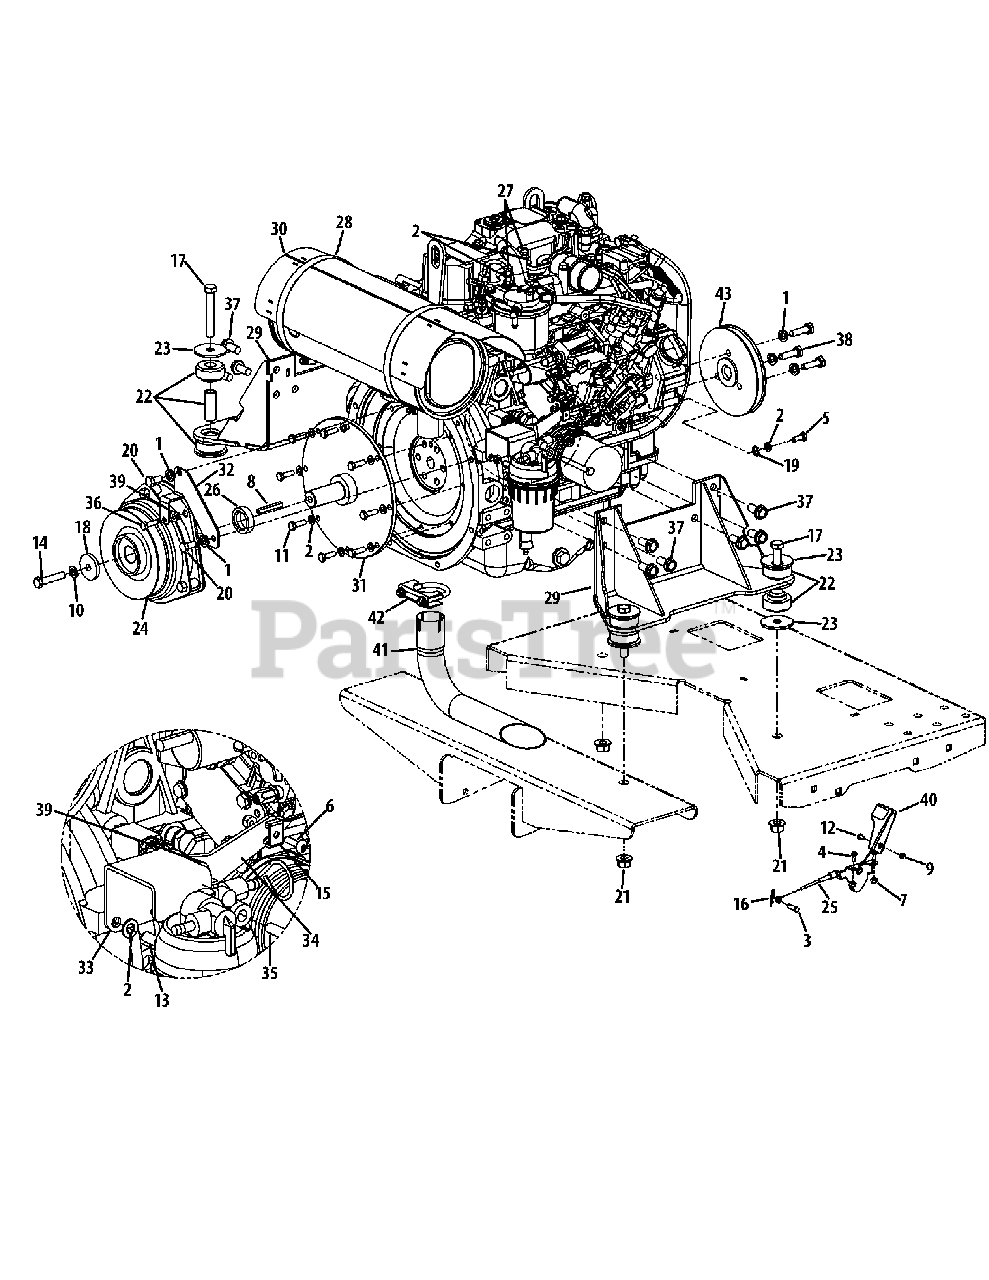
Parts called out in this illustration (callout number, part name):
1	Washer, 10 x 17.8 x 3.6
2	Lock Washer, .312 x .583 x .083
3	Clevis Pin, 1/4 x .750
4	Hex Flange Screw, #10-32 x .500
5	Hex Screw, M8-1.25 x 18
6	Machine Screw, #10-32 x .625
7	Nut, #10-32
8	Key, .250 x .250 x 2.00
9	Nut, #8-32
10	Lock Washer, .490 x .776 x .114
11	Hex Screw, M8-1.25 x 25
12	Machine Screw, #8-32 x .356
13	Hex Screw, M8-1.25 x 20
14	Hex Screw, 7/16-20 x 2.00
15	Cable Throttle Clamp
16	Hair Pin, 1/8 x 1.125 x .072
17	Hex Screw, 1/2-13 x 3.25
18	Washer, .438 x 1.745 x .250
19	External Tooth Washer
20	Hex Screw, M10-1.5 x 20
21	Flange Top Lock Nut, 1/2-13
22	Engine Isolater
23	Washer, .53 x 2.13 x .134
25	Throttle Control Cable
26	Spacer, 1.14 x 1.75 x .438
27	Hex Screw, M8-1.25 x 30
28	Hose Clamp
31	Clutch Drive Shaft
33	Diesel Fuel Seperator Mount Bracket
34	Throttle Mount Bracket
35	Hex Screw, 5/16-18 x 2.75
36	Hex Screw, 5/16-18 x 1.00
37	Hex Flange Screw, M12-1.75 x 25
38	Hex Screw, M10-1.5 x 35
39	Flange Lock Nut, 5/16-18
40	Throttle Control Knob
41	Elbow Exhaust Pipe
42	Muffler Clamp
43	Transmission Drive Pulley
